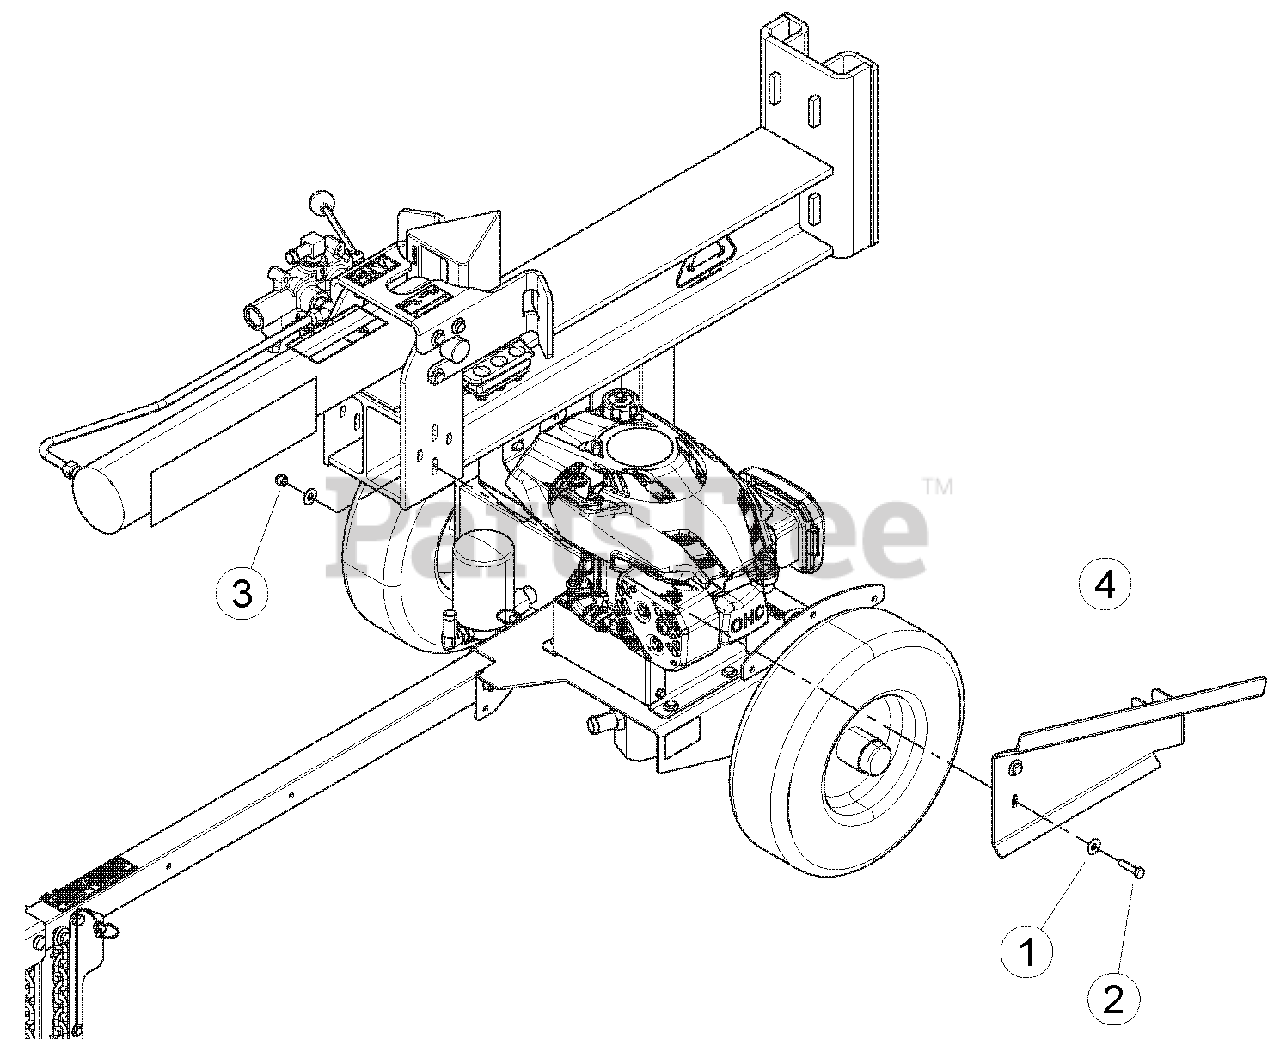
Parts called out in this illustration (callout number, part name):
1	WASHER, 3/8 FLAT ZP
2	BOLT, 3/8 X 1-1/4 HEX GR5 ZP
3	NUT, 3/8 NE NYLOCK ZP
4	CHUTE, ENGINE GUARD
